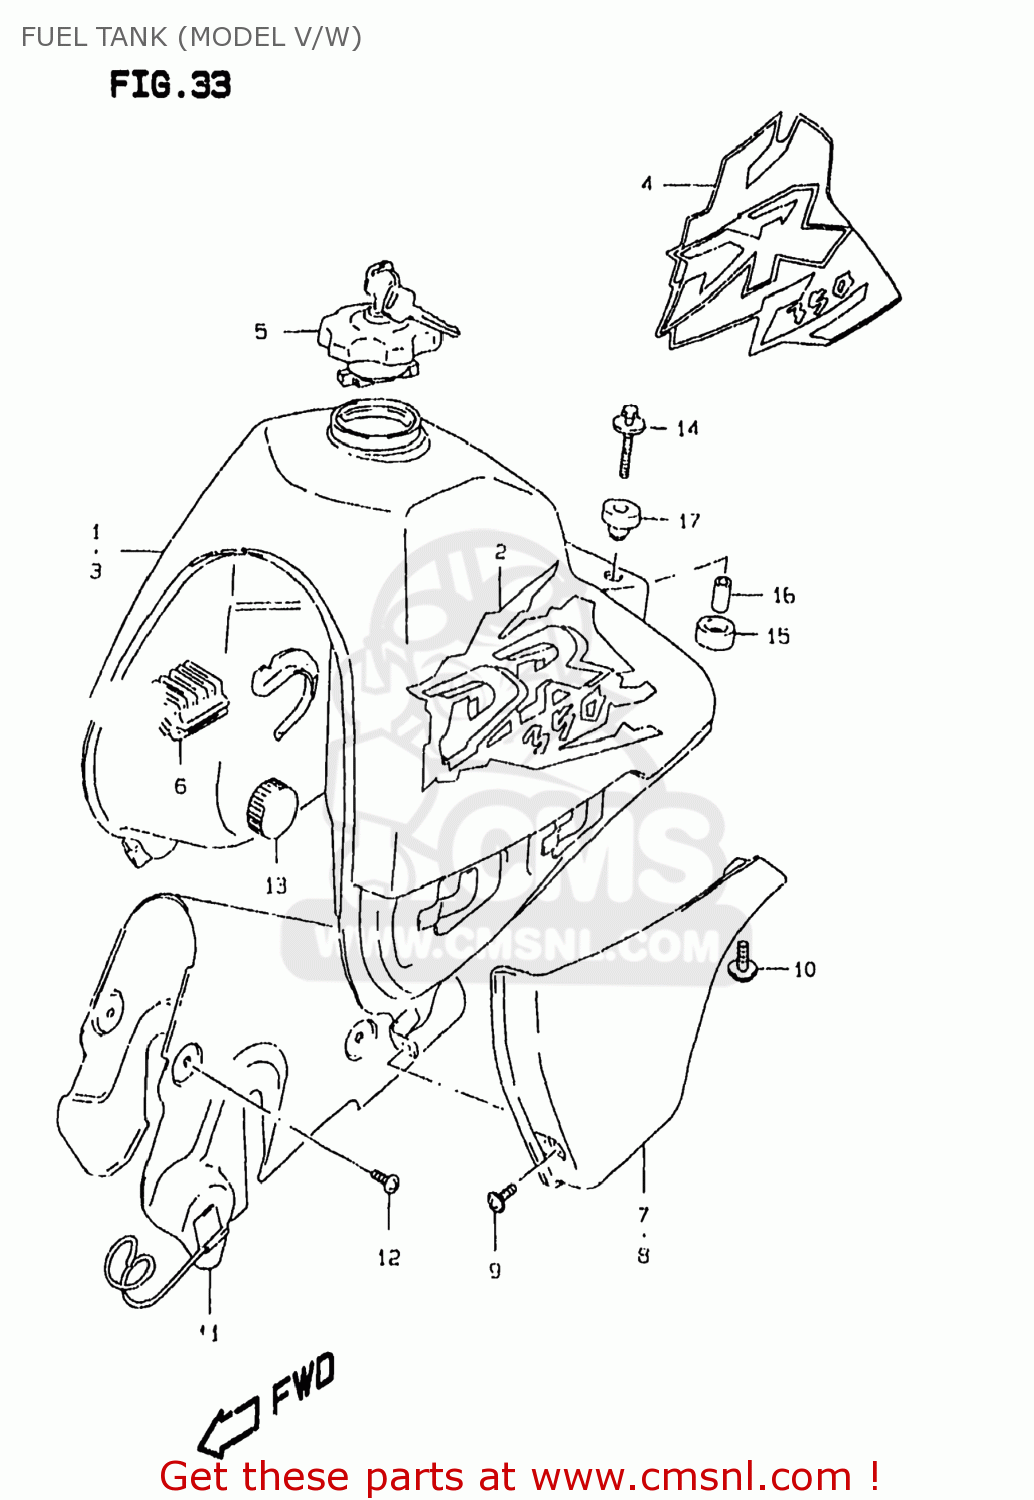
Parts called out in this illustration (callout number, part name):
1	TANK ASSEMBLY,FUEL
2	TAPE SET,FUEL TANK
3	TANK ASSEMBLY,FUEL
4	TAPE SET,FUEL TANK
5	CAP SET,FUEL TANK
6	CUSHION,FUEL TANK FR UPR
7	COVER,FUEL TANK,R
8	COVER,FUEL TANK,L
9	SCREW
10	SCREW(6X12)
11	SHIELD,FUEL TANK
12	BOLT
13	CUSHION
14	BOLT(6X30)
15	CUSHION
16	SPACER(6.5X9X18)
17	CUSHION
